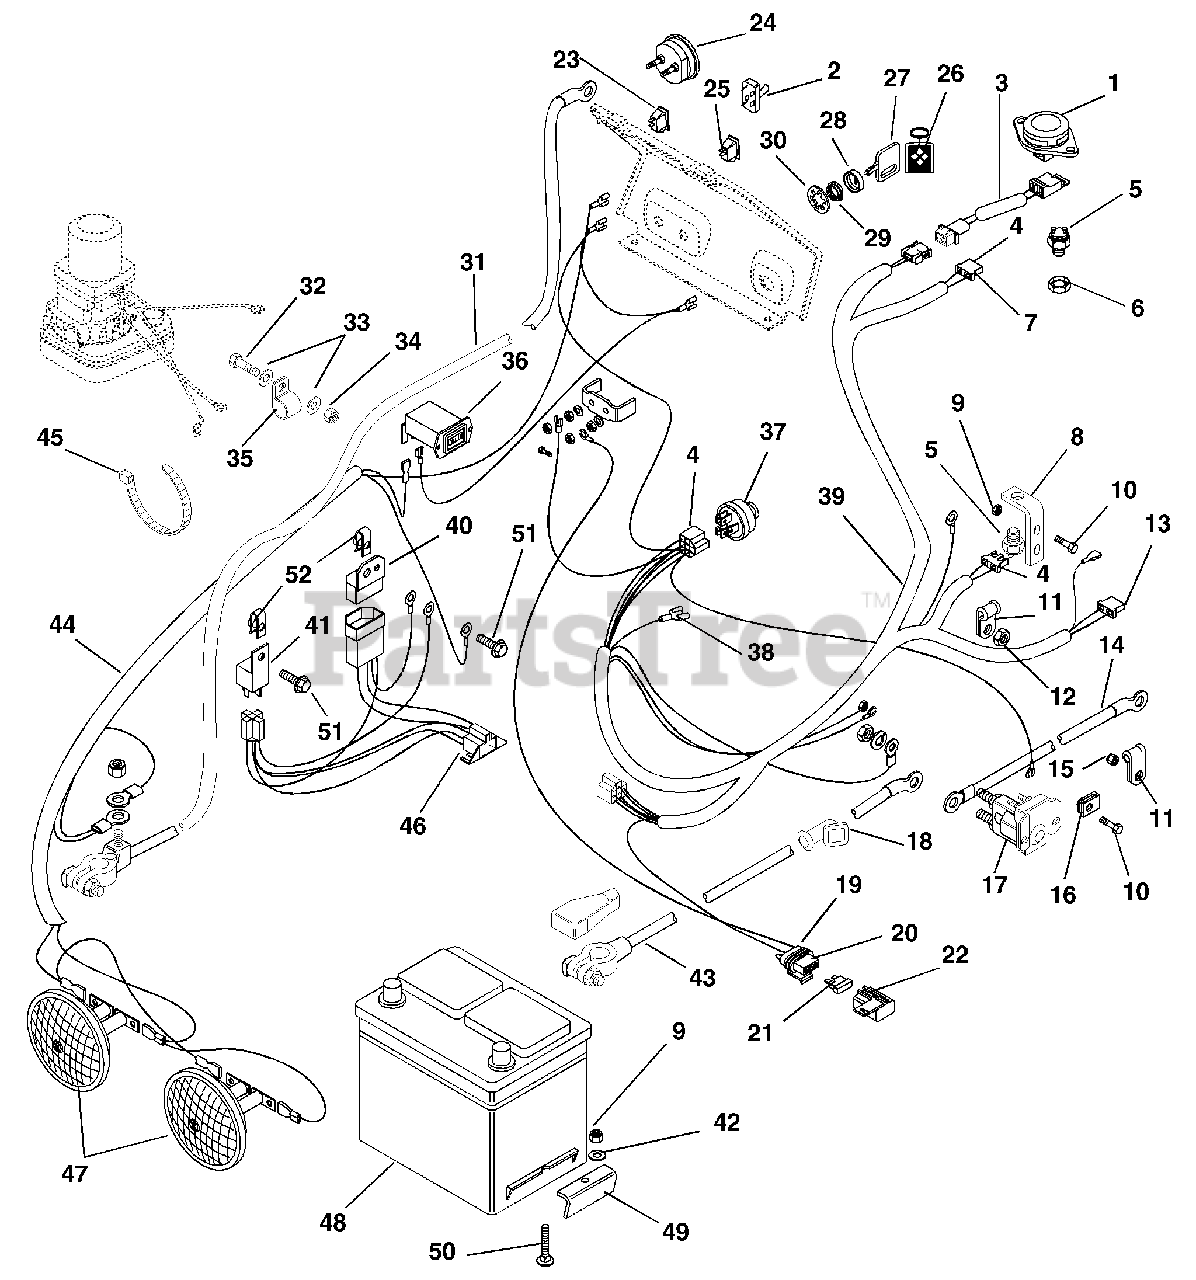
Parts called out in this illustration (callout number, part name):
1	Switch, Seat
2	Assembly, Switch
3	Harness, Wiring Seat Switch
4	Terminal
5	Switch-Neutral Start (N.O.)
6	Nut-Stamped .56-18
7	Connector, 2-Wire Switch
8	Bracket, Switch
9	Nut-Locking-Center .25-20
10	Bolt-Hex .25-20 x .75 Grade 5
11	Clamp
12	Nut-Locking-Center .38-16
13	Connector
14	Cable, Starter
15	Nut-Locking-Center .38-16
16	Nut-Speed .25-20
17	Solenoid
18	Boot, Insulator
19	Assembly, Connector Weather Tight
20	Terminal For 14-16 Gauge Wire
21	Fuse, 25 AMP
22	Cover
23	Light, Indicator
24	Gauge, Ammeter
25	Switch, Light
26	Key Chain
27	Key With Cap
28	Cap, Ignition Switch
29	Nut-Panel .56-24
29	Nut-Panel .625-32
30	Washer-Locking-Internal .56 x .040
30	Washer-Locking-Internal .63 x .045
31	Cable, Negative Battery
32	Bolt-Hex .31-18 x 1.00 Grade 5
33	Washer-Flat-Steel .34 x .69 x .065
34	Nut-Locking-Center .31-18
35	Clamp-Steel 1.00
36	Hour Meter
37	Switch, Key
37	Switch,Key
38	Connector
39	Harness, Wiring
40	Module, Interlock Delay
41	Relay
42	Washer-Flat-Steel 28 x .62 x .065
43	Cable, Battery To Magneto Switch
44	Harness, Wiring Ground and Lights
45	Cable Tie
46	Adapter, Module
47	Head Light
48	Battery
49	Clamp
50	Bolt-Round Head Square Neck .25-20 x 1.75 Grade 5
51	Screw-Machine 10-24 x .75 Hex Washer Head
52	Nut-Retaining Ring 10-24
